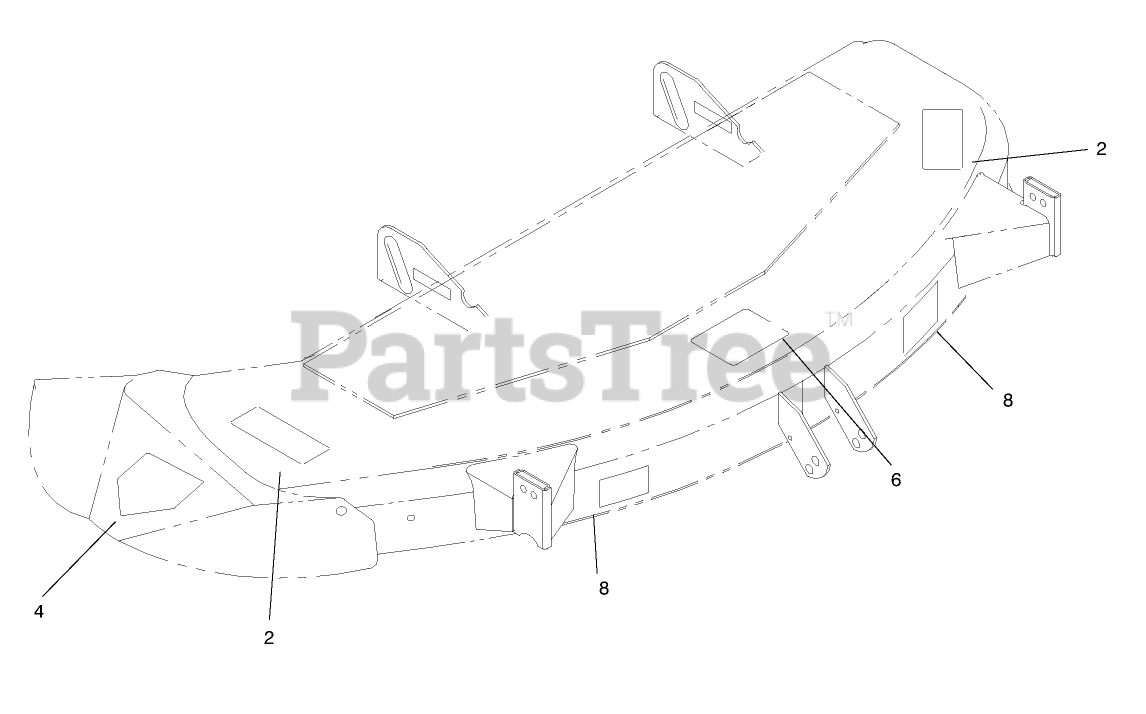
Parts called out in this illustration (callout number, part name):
2	DECAL-DANGER
4	DECAL-DANGER
6	DECAL-BELT INSTALL
8	DECAL - WHEEL ADJUSTMENT
